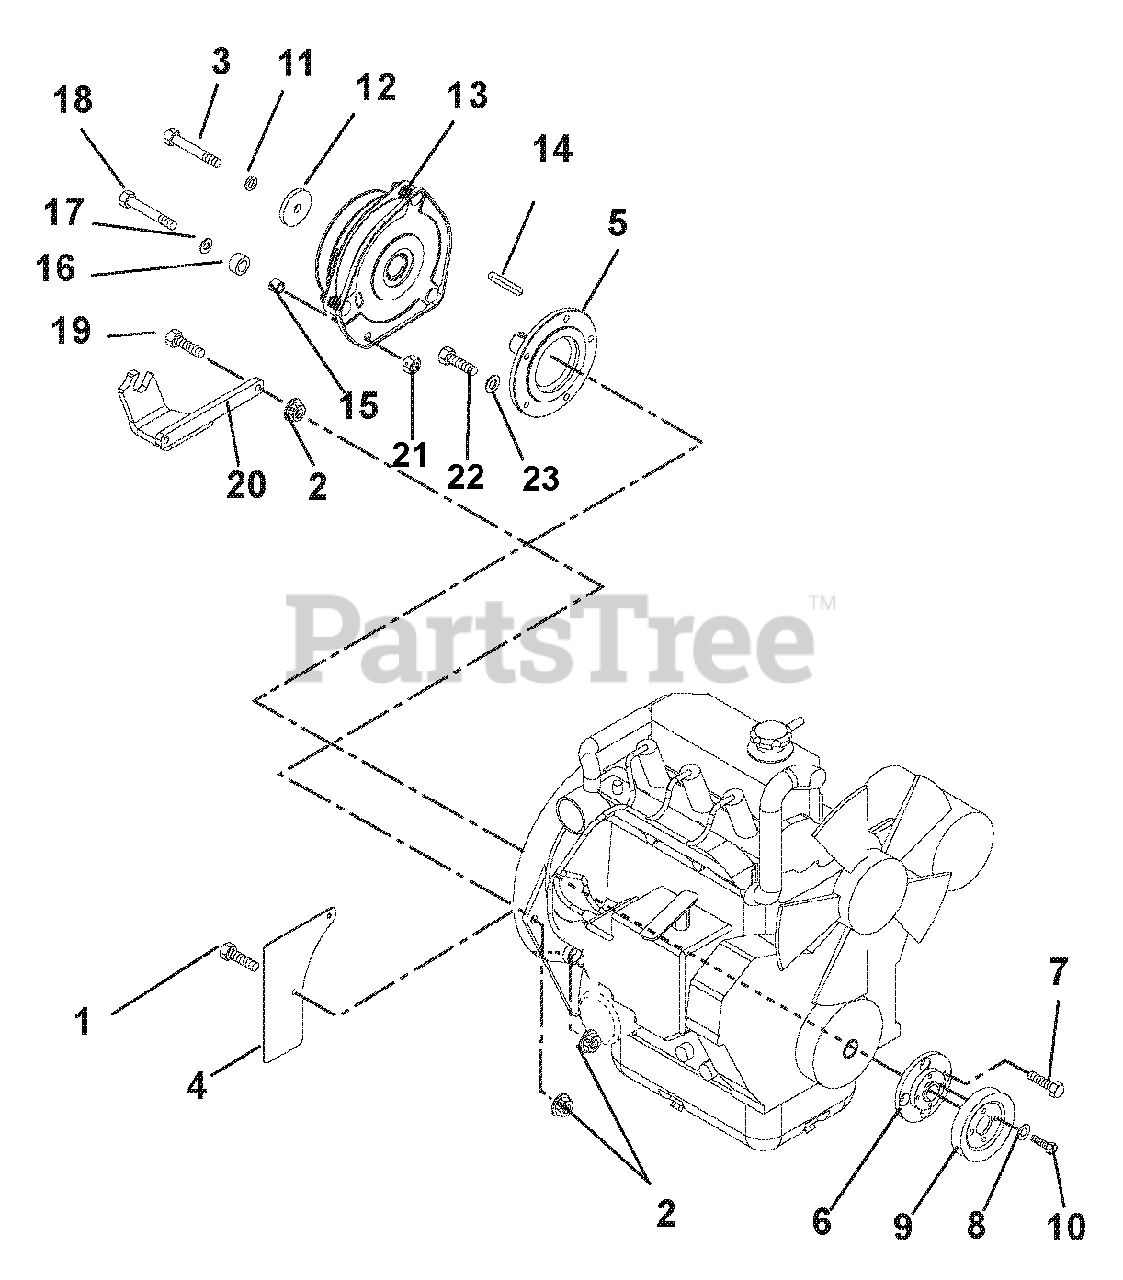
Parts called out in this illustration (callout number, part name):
1	Bolt, Hex .31-18 x .75 Grade 5
2	Nut, Locking Top Flange .31-18
3	Bolt, Hex .44-20 x 2.50 Grade 5 YZ EP80
4	Guard, Flywheel
5	Stub Shaft
6	Adapter, Sheave
7	Bolt, M8 1.25 x 25
8	Washer, Locking .25 x .062
9	Sheave, Poly V 1.0 x 3.25
10	Bolt, Hex .25-20 x .75 Grade 5
11	Washer, Locking .44 x .109 Regular
12	Washer, Flat Steel .469 x 2.00 x .25
13	Clutch, Ogura
14	Key .25 x .25 x 2.25
15	Spacer .375 x .688 x .500
16	Bumper, Rubber .62 x 1.0 x .51
17	Washer, Flat Steel .406 x .812 x .065
18	Bolt, Hex .38-16 x 1.00 Grade 5
19	Bolt, Hex .31-18 x 1.25 Grade 5
20	Bracket, Clutch Stop
21	Nut, Lock .375-16
22	Bolt, Hex M8 x 1.25 x .75 Grade 8
23	Washer, Lock .31 x .078 Reg
